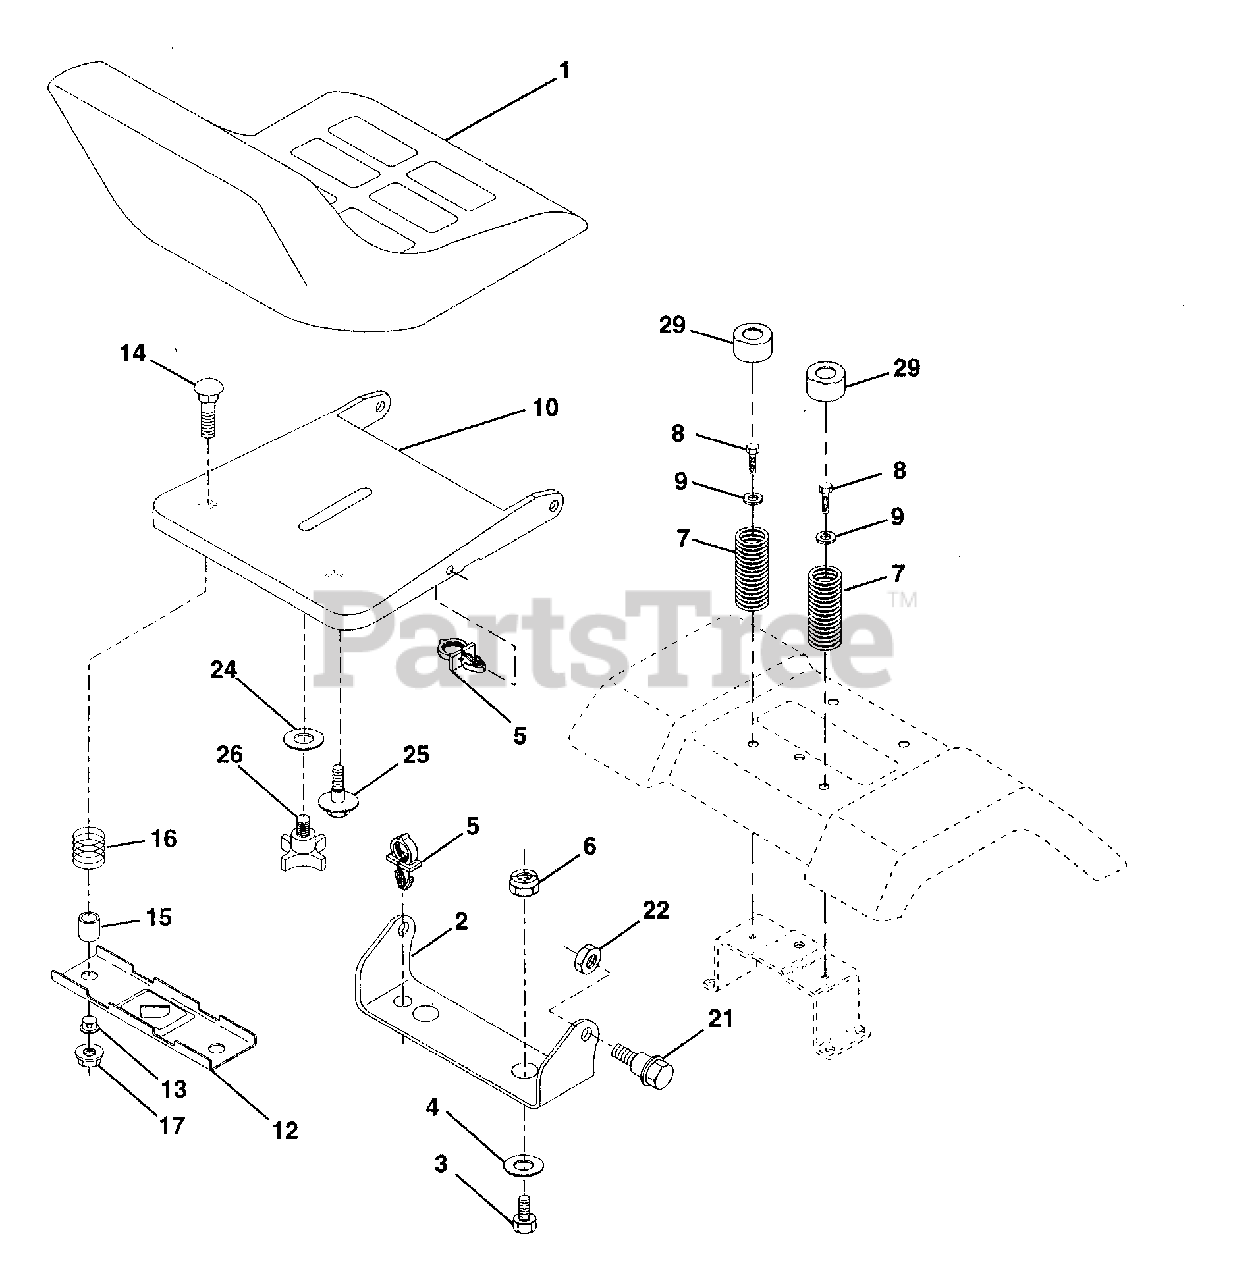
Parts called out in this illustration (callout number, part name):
1	Seat V350 Blk/blk Std
2	Bracket Pivot Seat 8 720
3	Bolt Fin Hex 3/8-16unc X 1
4	Washer 13/32 X 3/4 X 10 Ga
5	Clip Push-In .375 x .250
6	Nut Lock Hex w/Ins 3/8-16 Unc
7	Spring Seat Cprsn 2 250 Blk Zi
8	Screw Thdrol 3/8-16 X 1 Ty-tt
9	Washer 13/32 X 1 X 14 Ga
10	Pan Seat
12	Bracket Mounting Switch
13	Bushing Snap Blk Nyl 50 Id
14	Bolt Rdhd Sht Nk 1/4-20x1-3/8
15	Spacer Split 28x 96 Yel Zinc
16	Spring Cprsn 1 27 Blk Pnt
17	Nut Lock 1/4 Lge Flg Gr 5 Zinc
21	Bolt Shoulder 5/16-18 Type T.T.T.R.
22	Nut Lock 5/16-18
24	Washer 17/32 X 1-3/16 X 12 Ga
25	Bolt Shoulder 5/16-18 X 62
26	Knob Seat 1/2-13unc Blk
29	Cap Spring Seat Blk 1.75 x 1.0
